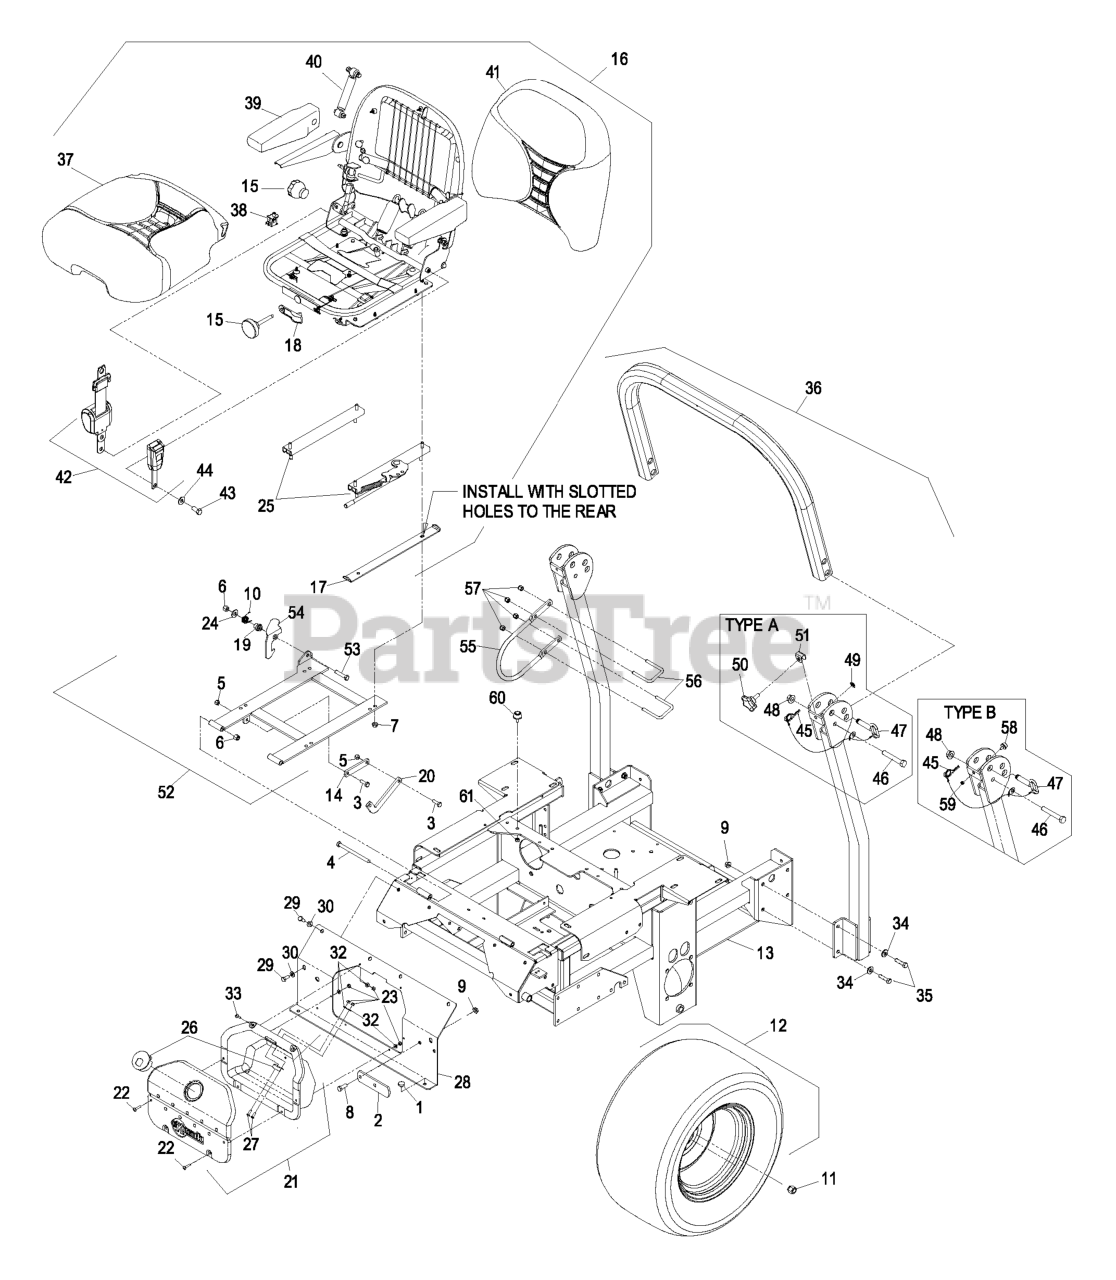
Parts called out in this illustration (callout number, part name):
2	STOP-BRAKE, PARK
3	SCREW-HH
4	SCREW-HH
5	NUT-LOCK, NI
6	NUT-LOCK, NI
8	SCREW-HH
9	NUT-HHF, WHIZ
10	SPRING-TORSION, LATCH
11	NUT-LUG
12	WHEEL AND TIRE ASM
14	LINK-STOP, SEAT
15	KNOB KIT
16	Lsseat Seat, Suspension
17	STOP-SEAT
18	WEIGHT INDICATOR KIT
19	BUSHING-LATCH, SEAT
20	LINK-STOP, SEAT
21	ASM,CUBBY
23	NUT-LOCK, NI
24	WASHER-FLAT
25	SEAT TRACK KIT
26	LATCH,CUBBY
27	SCREW-PPH
28	ASM, CONSOLE W/DECALS
29	SCREW-HH
30	WASHER-PLAIN
32	WASHER-FLAT
33	SCREW-HEAD, TRUSS
34	WASHER-BELLEVILLE
35	SCREW-HH
36	KIT, 06 XS ROPS
37	BOTTOM CUSHION KIT
39	PAD-ARMREST
40	SHOCK ABSORBER KIT
41	BACK CUSHION KIT
42	RETRACTABLE SEATBELT KIT
43	SCREW-HH
44	WASHER-SPRING
45	HAIRPIN
46	SCREW-HH
47	PIN-FOLD, ROPS
49	NUT-PUSH
52	SEAT FRAME SINGLE LATCH A
53	SCREW-HH
54	CATCH-LATCH, SINGLE
57	NUT-LOCK, NI
58	BUMPER-RUBBER
59	NUT-LOCK, NI
60	BUMPER-RUBBER
61	NUT-LOCK, NI
